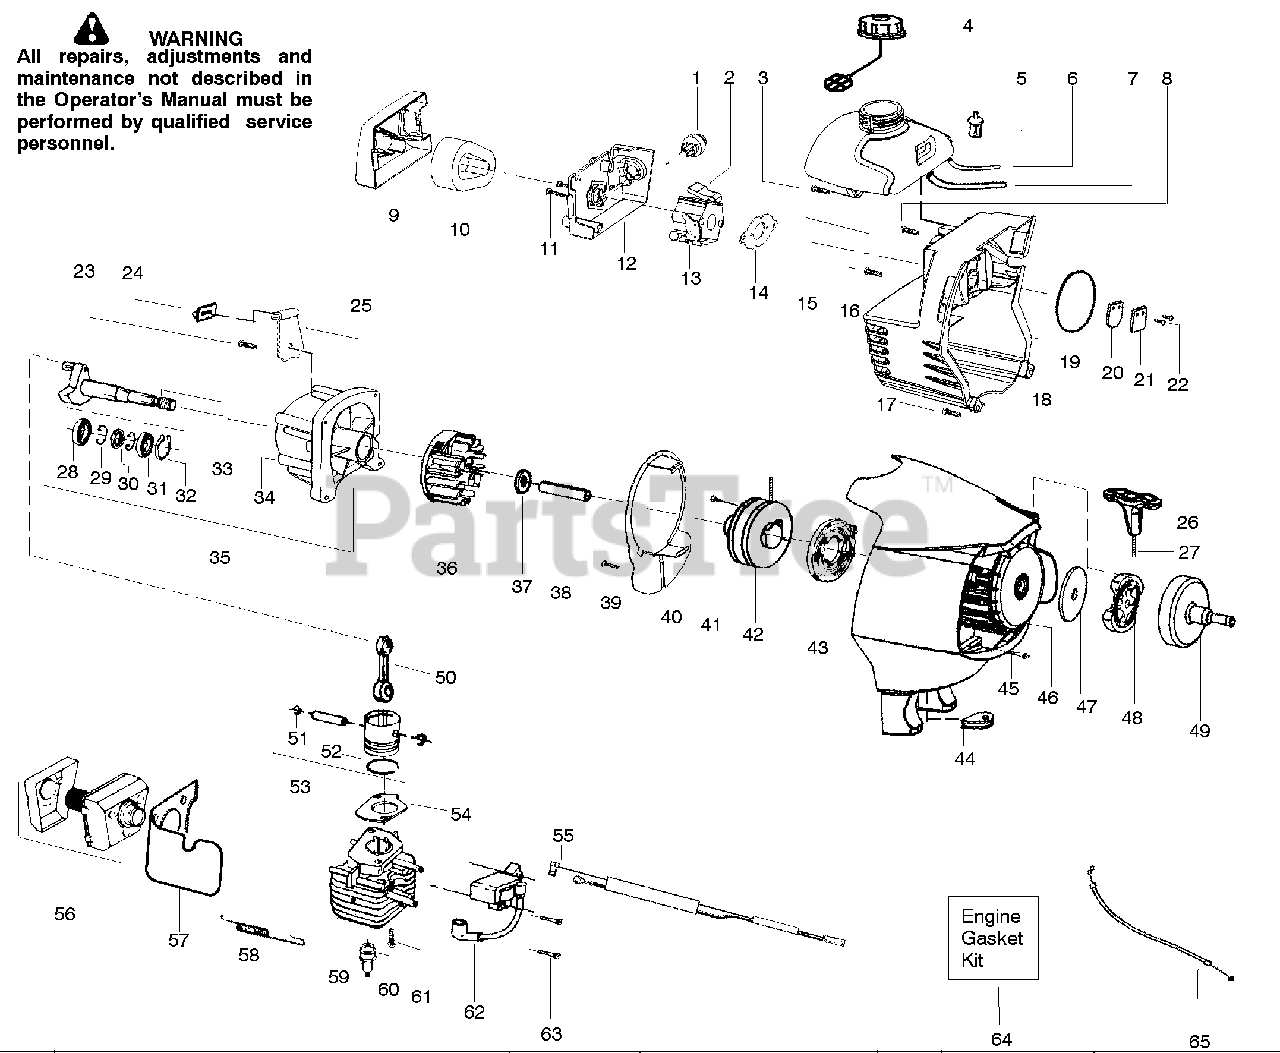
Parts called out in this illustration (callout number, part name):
2	Kit-Choke Lever
4	Cap-Fuel w/ret.
5	Assy-Fuel pickup
6	Kit-Fuel line
7	Kit-Fuel/Purge line
9	Cover-Air box
13	Assy-Carb(WT628)
14	Gasket-Carb.(kit)
15	Assy-Fuel Tank
16	Screw-Crankcase
19	O-ring-Shroud (kit)
22	Screw-Reed stop
23	Screw-Retainer
24	Isolator-Tank
26	Handle-Starter
28	Bearing-Inner
31	Bearing-Outer
32	Ret.-Crankshaft
33	Assy-Crankshaft
34	Assy-Crankcase
35	Assy-C'case/C'shaft
36	Assy-Flywheel
40	Plate-Baffle
42	Kit-Pulley
43	Spring-Starter
45	Screw-F/hsg.
46	Assy.-Fan Housing
47	Washer-Clutch
49	Drum-Clutch
50	Assy-Conn. Rod
51	Ret.-Piston pin
53	Kit-Piston
54	Gasket-Cylinder(kit)
55	Assy-Leadwire
58	Spring-Muffler
59	Cylinder
60	Plug-Spark(RCJ-6Y)
61	Bolt-Cyl. 1/4-20"
62	Module-Ignition
64	Kit-Gasket
65	Assy-Throttle cable
